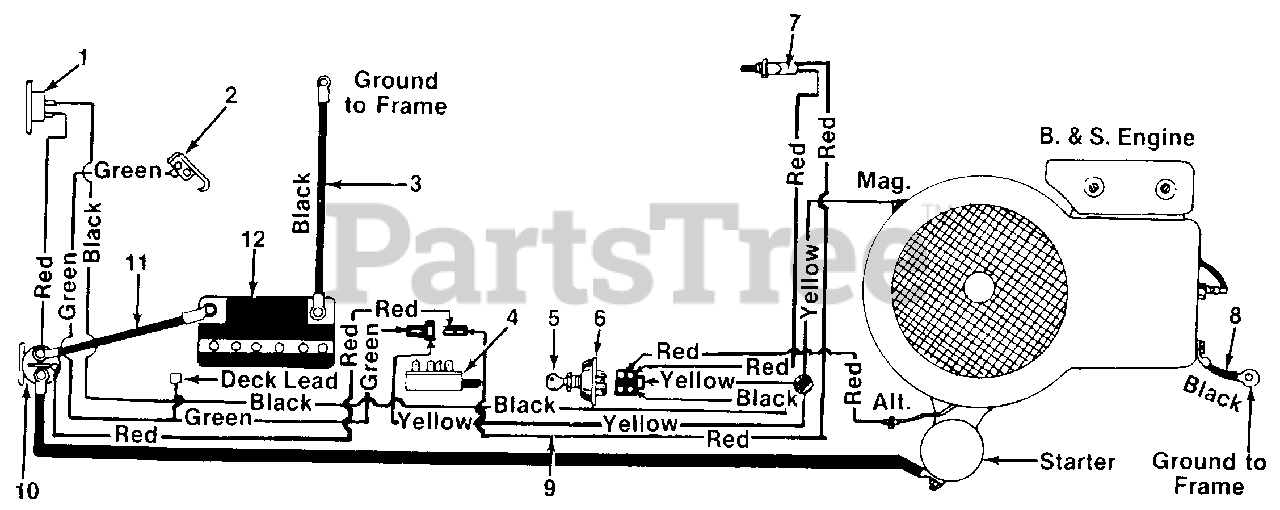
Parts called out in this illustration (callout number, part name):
1	Circuit Breaker
2	Spring Switch
3	Ground Wire 9.0" Lg.
4	Safety Switch
5	Ignition Key
6	Ignition Switch
7	Safety Switch
8	Ground Wire 7.25" Lg. (Black)
9	Wire Harness
10	Solenoid
11	Electric Wire w/Boot
12	1 2V-Battery
